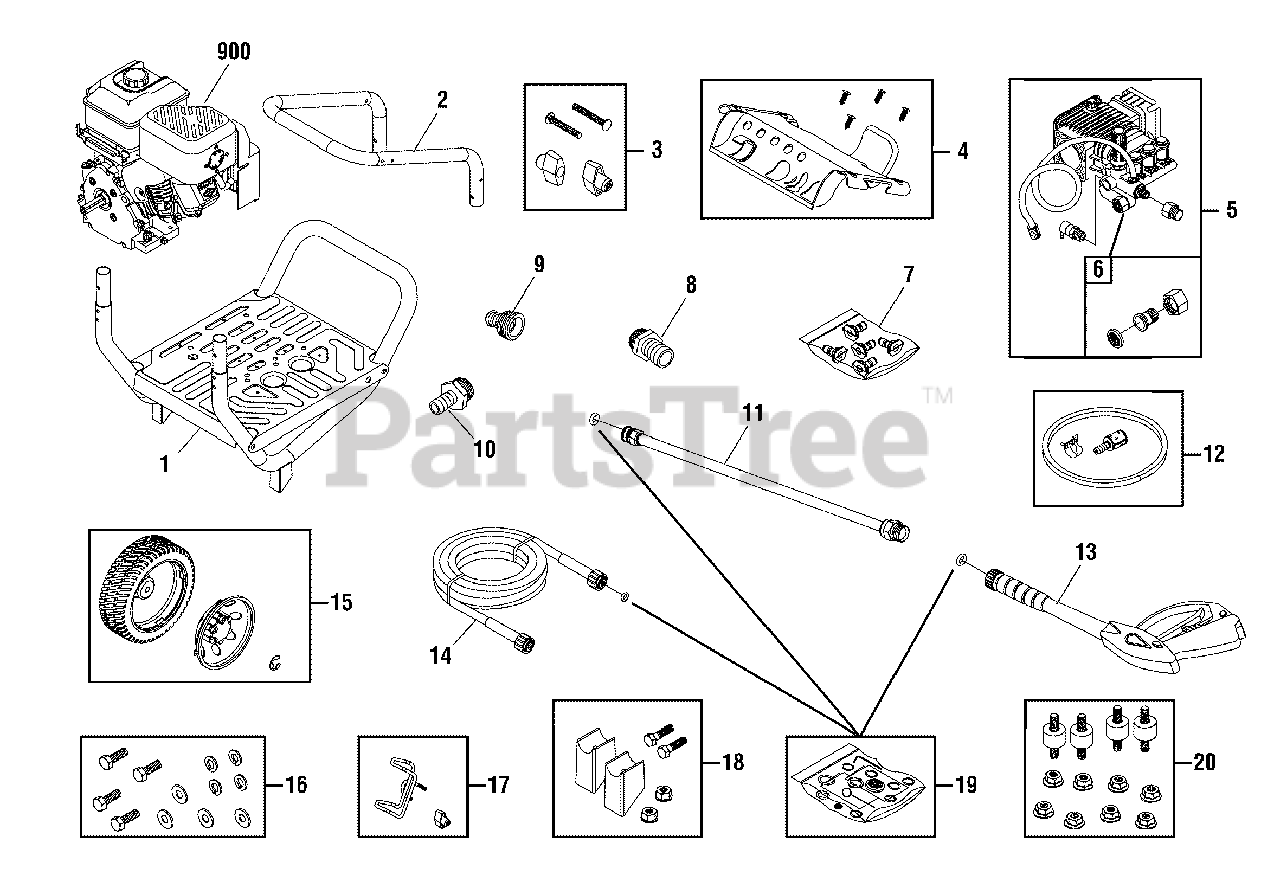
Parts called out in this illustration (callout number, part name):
3	KIT, Hardware, Handle
6	ADAPTER, Garden Hose
7	KIT, QC Nozzles
9	QC, Male
11	EXTENSION, QC
13	GUN
16	KIT, Hardware, Pump Mounting
18	KIT, Vibration Mount
19	KIT, 0-Ring
20	KIT, Vibration Mount
900	* ENGINE
